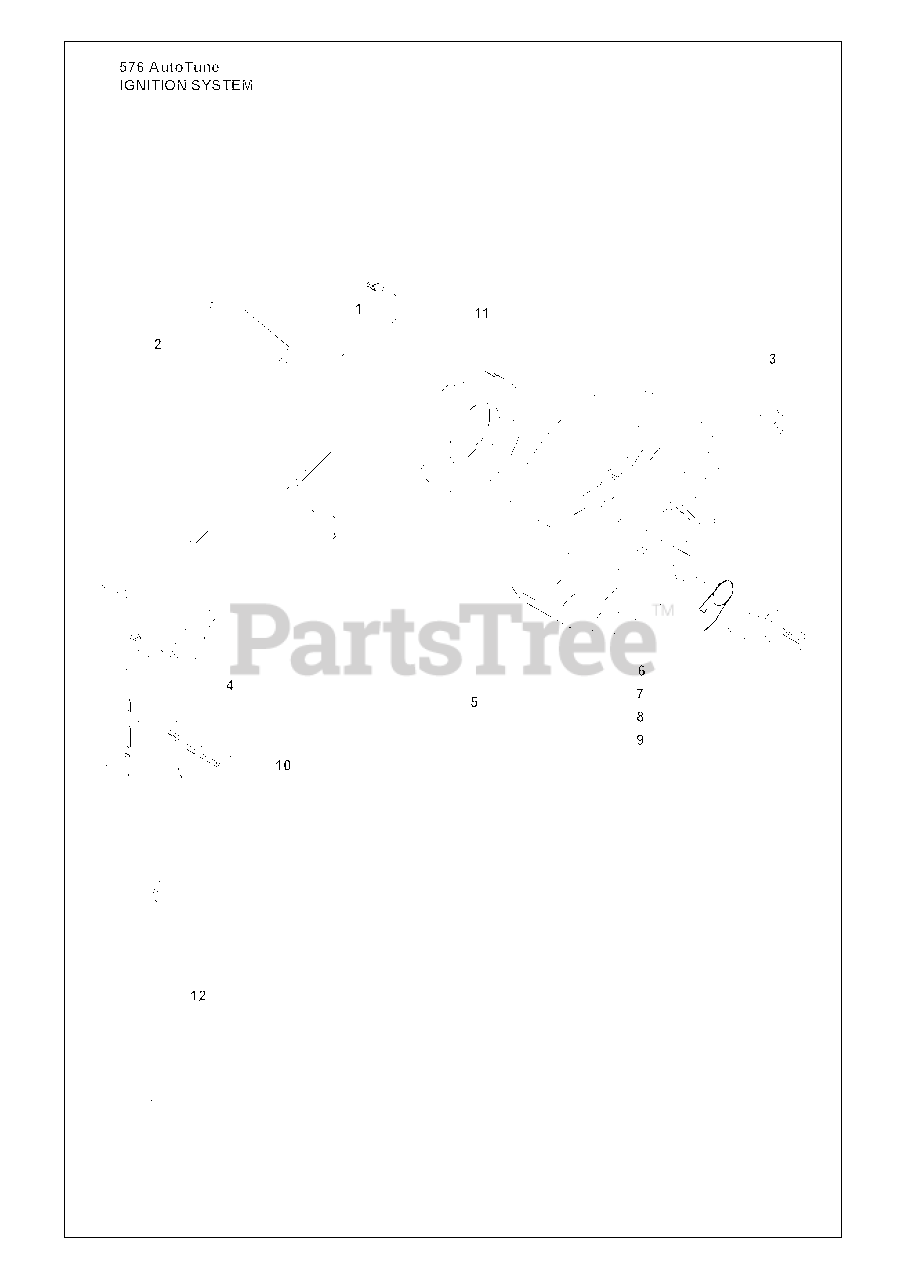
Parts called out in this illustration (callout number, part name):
1	SHORTING LEAD
2	SPARK PLUG CONN. KIT
3	NUT W/ WASHER
4	IGNITION MODULE
9	SCREW M5X14
11	GENERATOR
